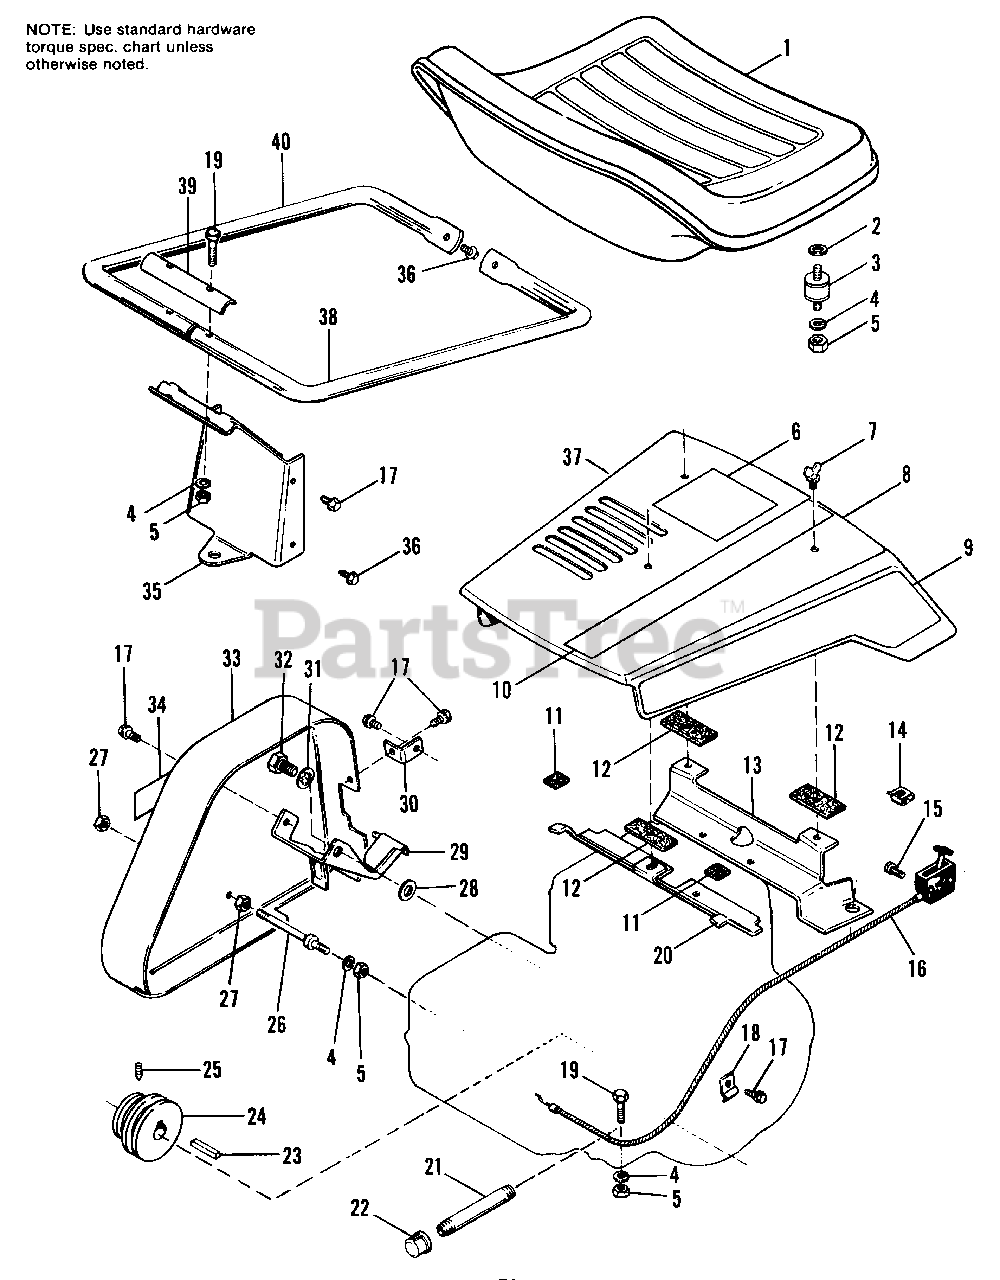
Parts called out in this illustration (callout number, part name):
1	SEAT ASSY.
2	WASHER, Plain, 5/16
3	CONNECTOR, Cushion
4	LOCKWASHER, 5/16
5	NUT, Hex, Full, 5/16-18
6	DECAL, Safety
7	SCREW, Wing, 5/16-18 x 3/4
8	HOOD ASSY.
9	DECAL, Hood, L.H.
10	DECAL, Stripe
11	BUTTON, Bumper
12	GASKET, Felt
13	SUPPORT, Front Hood
14	NUT, Retainer, 5/16-18
15	SCREW, Hex, Washer Hd., #10-24 x 1
16	THROTTLE & CHOKE ASSY.
17	SCREW, Taptite, Hex, 5/16-18 x 1/2
19	CAPSCREW, Hex Hd., 5/16-18 x 1-1/2
20	SUPPORT, Rear Hood
21	NIPPLE, Pipe
22	CAP, Pipe
23	KEY
25	SETSCREW, 5/16-18 x 5/16
27	LOCKNUT, Hex, 5/16-18
28	WASHER, Plain, 1/2
29	STOP, Belt
30	BRACKET, Pulley Guard
31	LOCKWASHER, Int., 1/2
32	CAPSCREW, Hex Hd., 1/2-20 x 1
33	GUARD, Pulley
34	DECAL, 3005
35	PLATE, Hitch, Rear
36	SCREW, Tapping, 1/4-20 x 1/2
37	DECAL, Hood, R.H.
38	HANDLE, Rear, R.H.
39	BRACKET, Support Handle
40	HANDLE, Rear, L.H.
